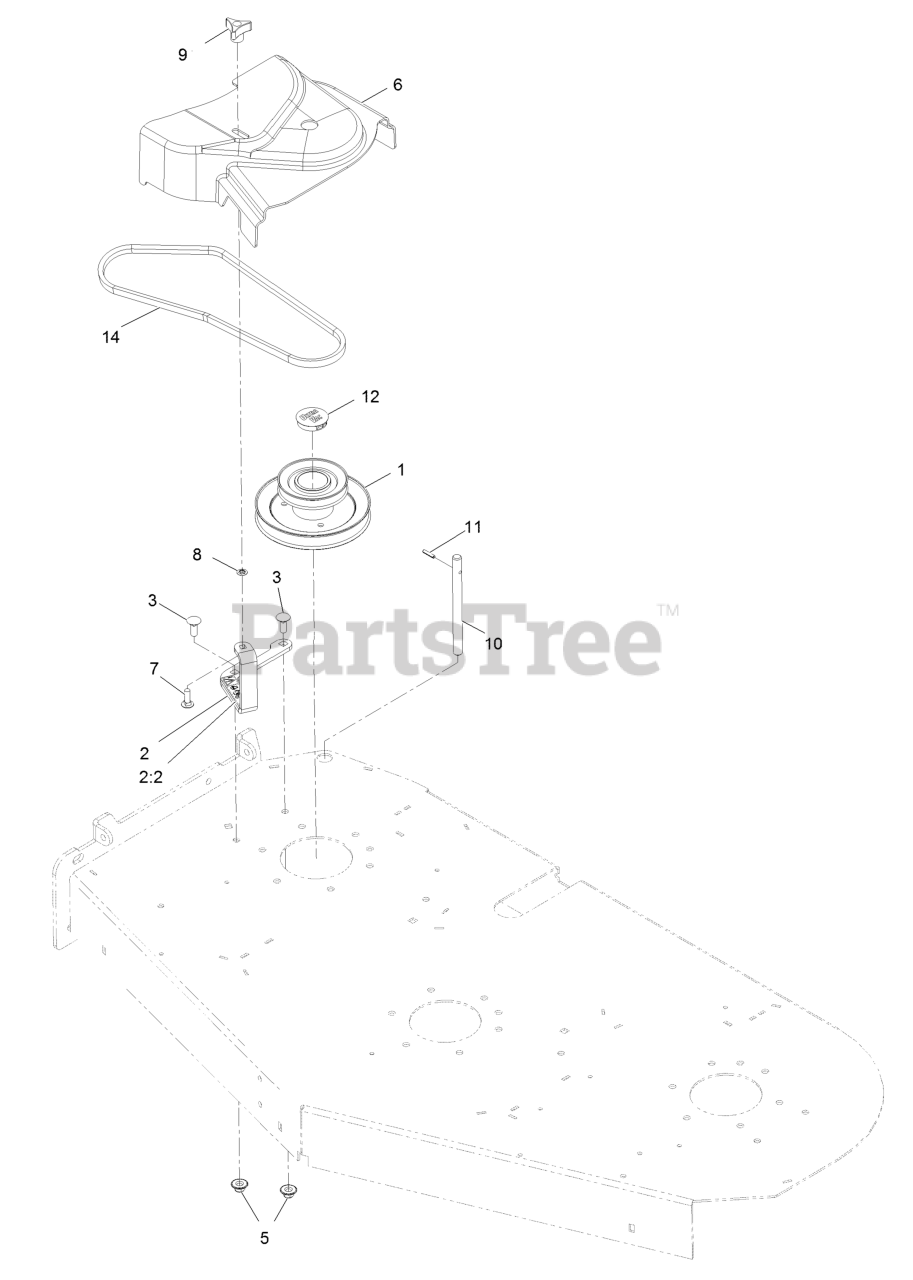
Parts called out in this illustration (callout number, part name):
1	Jackshaft-Uv Drive 523
2	ASM-Cvr Brkt W/Decal
2:2	Decal-Danger
3	Bolt-Carriage 3/8-16 X 1
5	Nut-Nyloc 3/8-16 Flg
6	Cover-Belt, Uv 52
7	Bolt-Carriage 5/16-18 X 1
8	Ring-Bolt Retaining
9	Knob-3 Prong
10	Shaft-Catcher, Grass
11	Rollpin 3/16 X 7/8
14	Belt, Blower Drive 52
